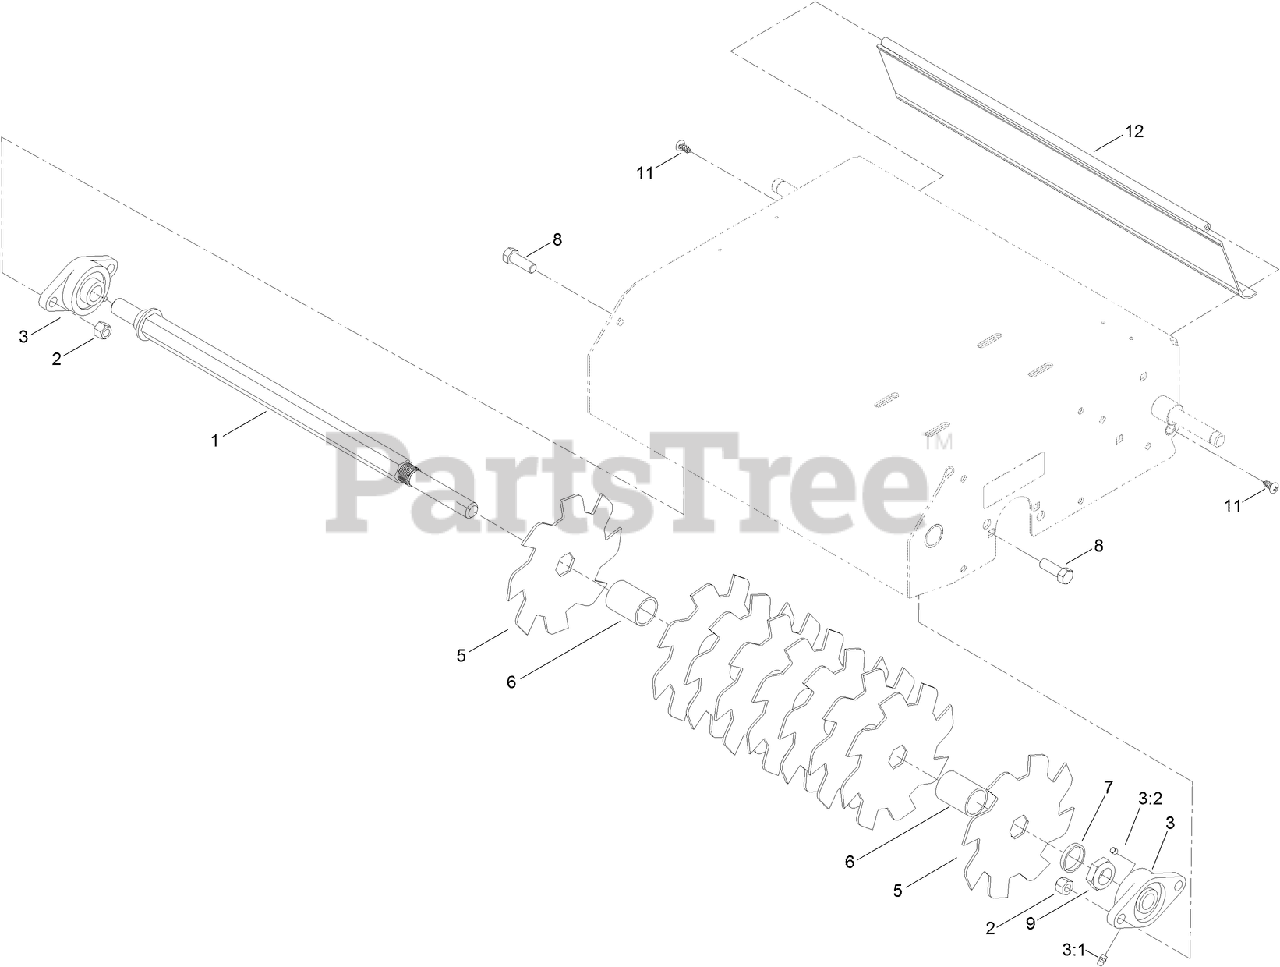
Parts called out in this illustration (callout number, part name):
2	NUT-LOCK, NI
3	BEARING-FLANGE
3:1	FITTING-STRAIGHT
3:2	SCREW-SET, HSH
5	BLADE-CUTTING, SEEDER
6	SPACER
7	SPACER-RETAINING
8	SCREW-HH
9	NUT-LOCK, NI
11	SCREW-PTH
12	SHIELD-TRAILING
